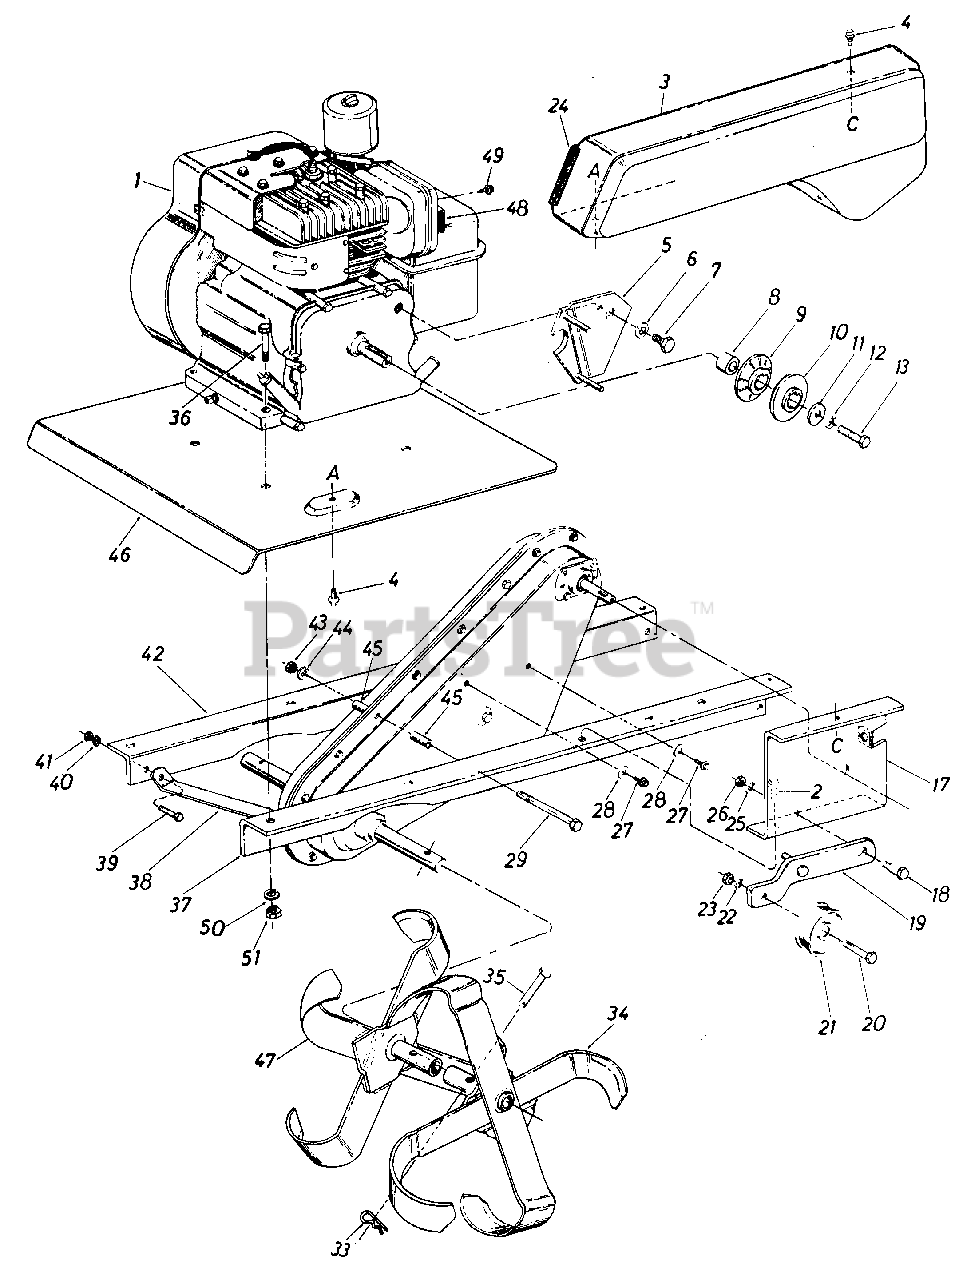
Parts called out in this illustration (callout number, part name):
1	Engine
2	Hex Wash. Hd. Self-Tap Scr. 5/16-24 x .50" Lg.
3	Belt Cover
4	Hex Wash. Hd. Self-Tap Scr. 1/4-20 x .50" Lg.
5	Belt Keeper Brkt. Ass'y.
6	Internal L-Wash. 1/2" I.D.
7	Hex Scr. 1/2-20 Thd.
8	Spacer
9	Pulley Half
10	Pulley Half
11	Fl-Wash. 3/8" I.D. x 1.25" O.D. x .100
12	L-Wash. 3/8" I.D.*
13	Hex Scr. 3/8-24 x 1.00" Lg.
17	Idler Mounting Brkt.
18	Shld. Bolt
19	Idler Bracket Ass'y.
20	Hex Scr. 3/8-16 x 1.50" Lg.
21	Idler Pulley
22	L-Wash. 3/8" I.D.*
23	Hex Jam Nut 3/8-16 Thd.
24	Trim Strip 3"
25	L-Wash. 3/8" I.D.*
26	Hex Jam Nut 3/8-16 Thd.
27	Hex Wash. Hd. Self-Tap Scr. 1/4-20 x .50" Lg.
28	BelleviIle Wash . .26 1. D. x .75 O.D. x .060
29	Hex Scr. 5/16-18 x 2.75" Lg.*
33	Hairpin Cotter
35	Clevis Pin
36	Bolt 5/16-18 x 1.5" Lg.*
37	Frame Rail L.H.
38	Front Brace Brkt.
39	Hex Scr. 5/16-18 x .75" Lg.*
40	L-Wash. 5/16" I.D.*
41	Hex Cent. L-Nut 5/16-18 Thd.
42	Frame Rail R.H.
43	Hex Cent. L-Nut 5/16-18 Thd.
44	L-Wash. 5/16" I.D.*
45	Spacer
46	Tine Shield
47	Inner Tine Ass'y. Comp. - R.H.
47	Outer Tine Ass'y. Comp. - R.H.
47	Inner Tine Ass'y. Comp. - L.H.
49	Hex Self-Tap Scr. #8-32 x.38" Lg.
50	L-Wash. 5/16" I.D.*
51	Hex Nut 5/16-18 Thd.*
